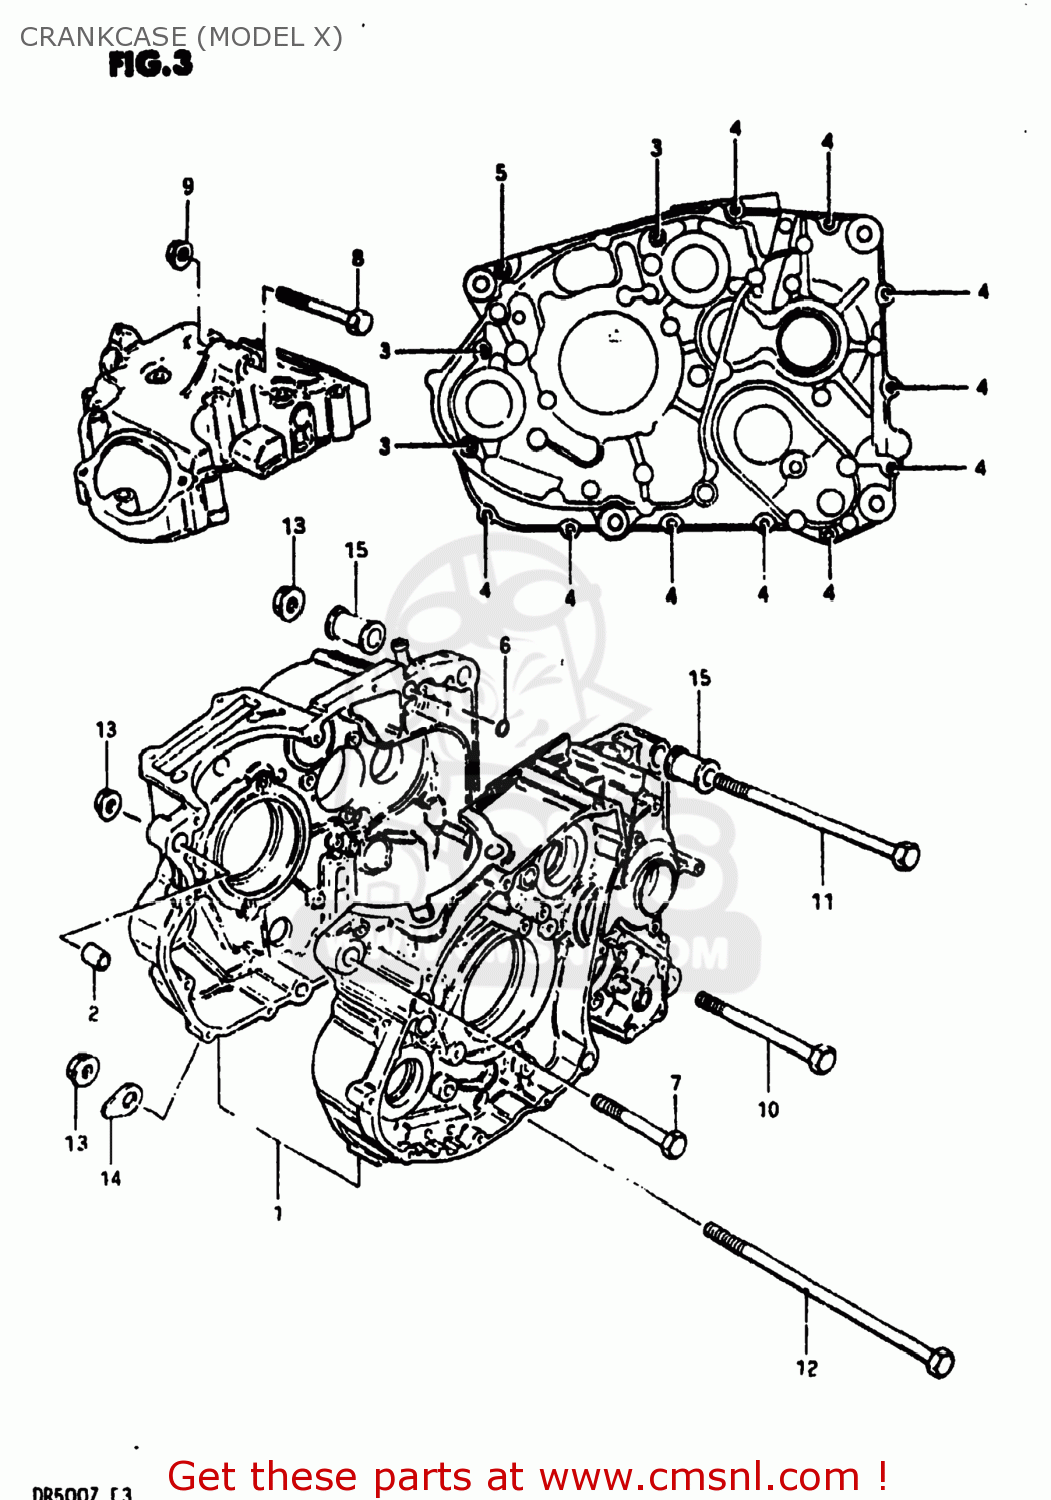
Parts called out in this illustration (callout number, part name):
1	CRANKCASE SET
2	PIN
3	SCREW 6X60
4	SCREW
5	SCREW 6X30
6	O-RING
7	BOLT(10X70)
8	BOLT
9	NUT
10	BOLT
11	BOLT
12	BOLT
13	NUT
14	WASHER
15	SPACER
